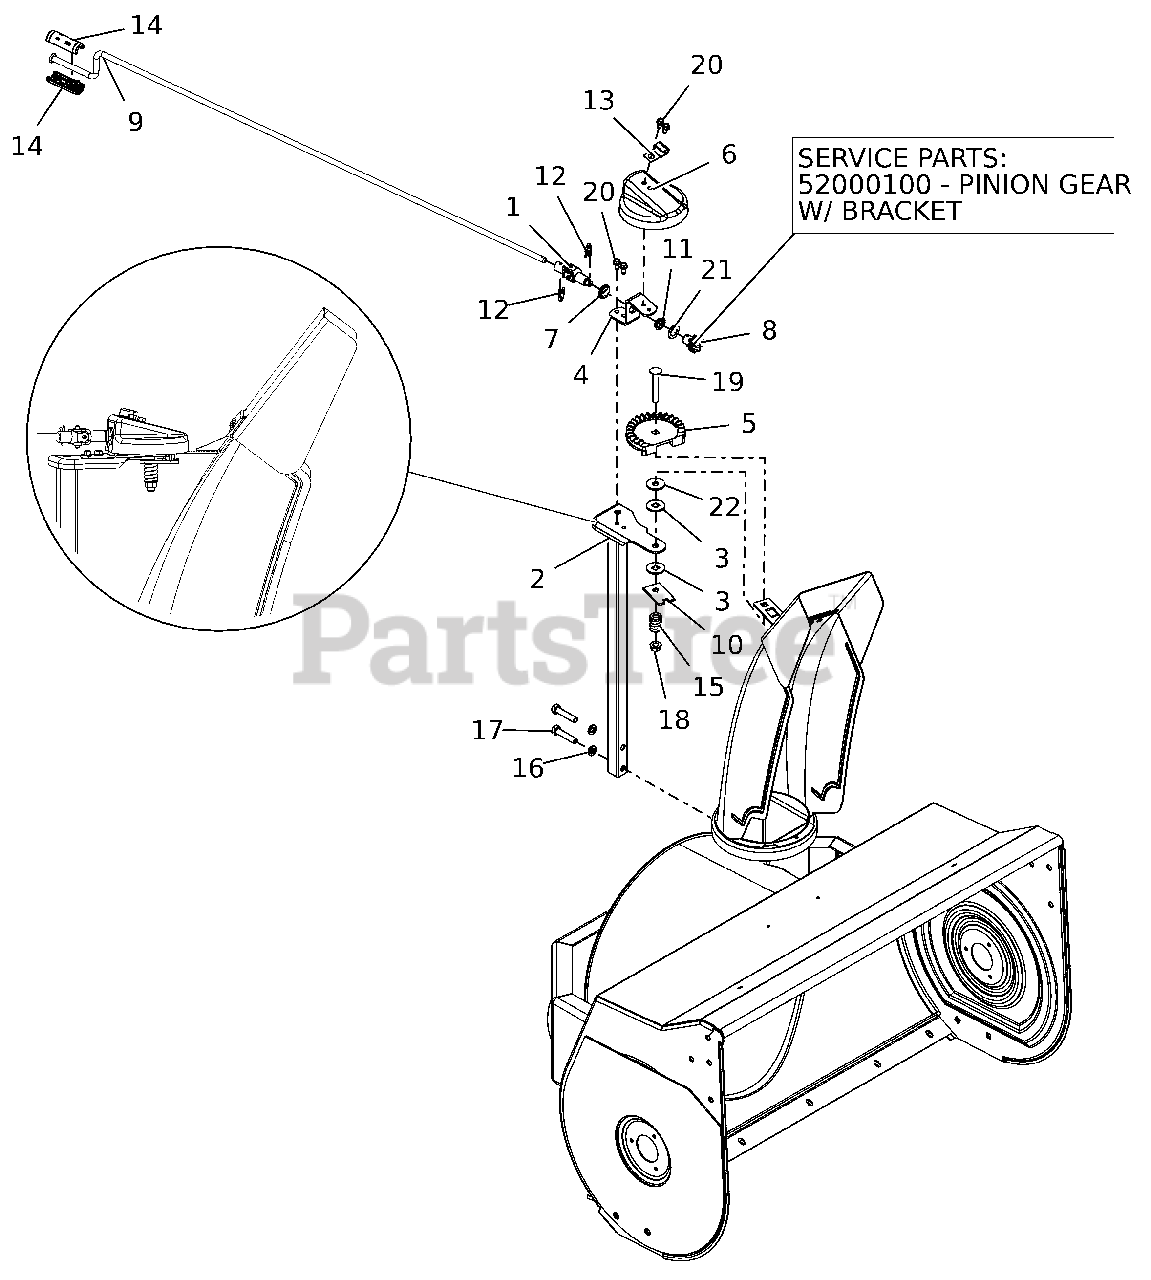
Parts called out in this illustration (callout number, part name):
1	ASS'Y, UNIVERSAL-W/PIN END
2	WLDMT, 32" CHUTE PEDESTAL
3	FRICTION WASHER
4	BRACKET, PINION GEAR
5	CHUTE GEAR
6	GEAR COVER
7	PUSHNUT .625
8	PINION GEAR - CHUTE
8	PINION GEAR W/BRACKET
9	CRANK,CHUTE
10	PLATE, FRICTION ZC120
11	BUSHING, POLYLINER-.63 SNAPIN
12	PIN, SPRING CLIP
14	KNOB, CHUTE CRANK - SNAP GRAY
15	SPRING,COMPRESSION
16	WSHR,LK-REG .375X.094 ZCC
17	BLT, HEX .38-16X1.75F G5 ZCC
18	NUT-LK-TOP-FLG .38-16 ZC120
19	BLT,RHSN .38-16X2.50 G5 ZCC
20	SCR-TAP .25-20X.50 HWH ZCC
21	WSHR-THRST .625 X 1.0 X .03
22	WSHR FL STL .406X1.25X.10ZC120
